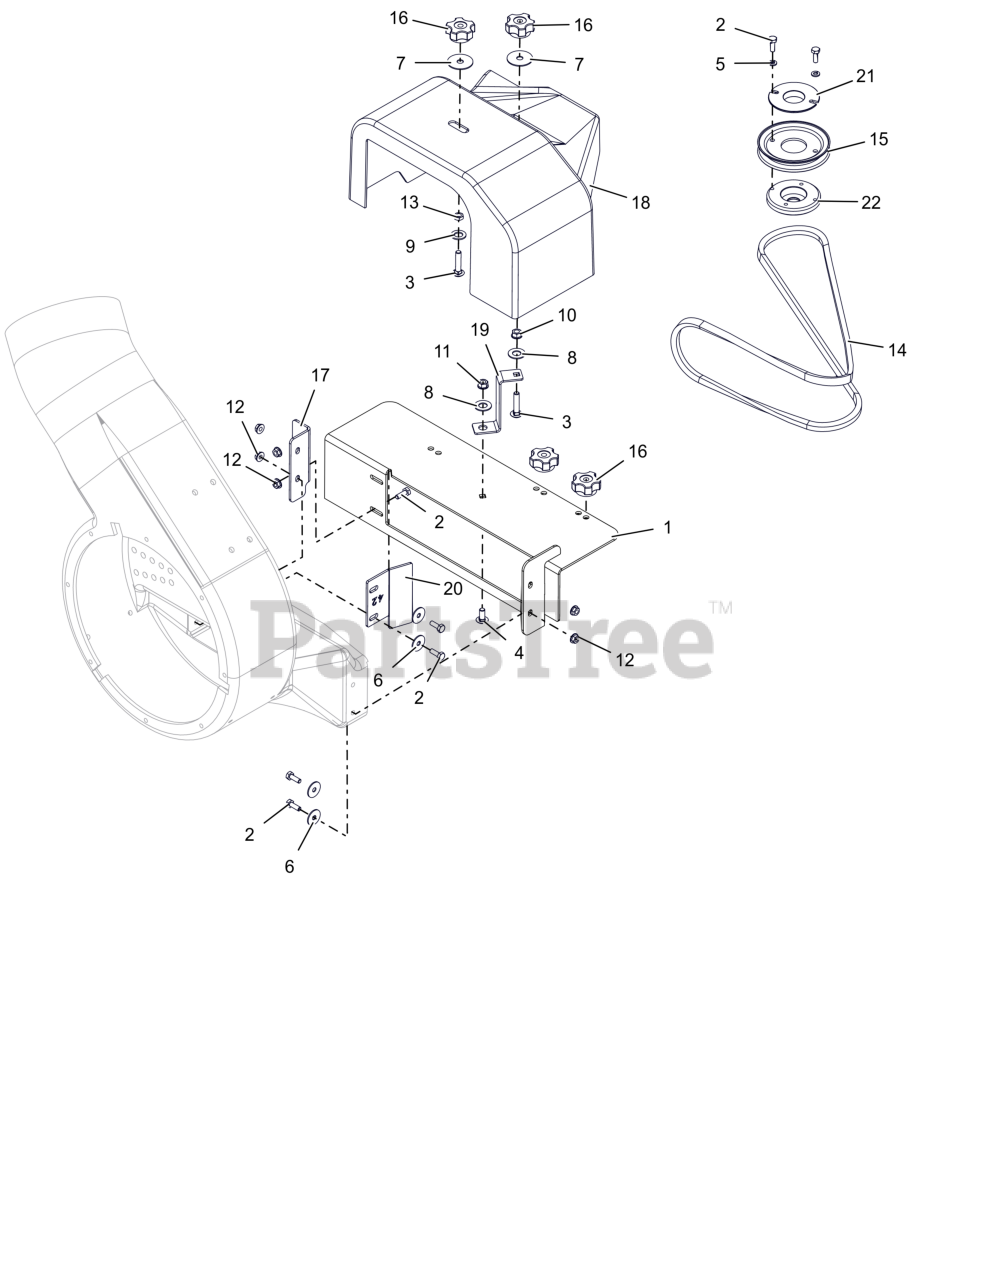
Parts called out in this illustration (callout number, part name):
1	WLDMT- BLOWER MTG
2	BLT, HEX .25-20X.75 G5 ZCC
3	BLT,RHSN .31-18X1.50 G5 ZCC
4	BLT, RHSSN.31-18X.750 G5 ZCC
5	WSHR,LK-REG .250X.062 ZCC
6	WSHR,FLT .281X1.000X.063 ZCC
7	WSHR,FLT .380X1.50X.062 ZCC
8	WSHR, FLT .505X1.00X.062 ZCC
9	WSHR, FLT .505X.880X.072 ZCC
10	NUT,SPNLK-FLG .31-18 G5 ZCC
11	NUT,LK-CTR-FLG .31-18 GF ZCC
12	NUT-LK-TOP-FLG .250-20 GF ZCC
13	NUT-JAM .312-18 G2 ZCC
14	V-BELT, 4L-RAW EDGE
15	PULLEY-V-4.25 ODX1.51 ID ZC120
16	KNOB-CLAMPING, .312-18 NYLOC
17	BRKT- BLOWER REAR MTG BLK
18	GUARD, 42" BLOWER BELT
19	BRKT, BLOWER GUARD MTG
20	BRKT- 42" BLOWER CLOSE-OFF
21	ADAPTER- BAGGER SHEAVE
22	ADAPTER- PULLEY IKON
